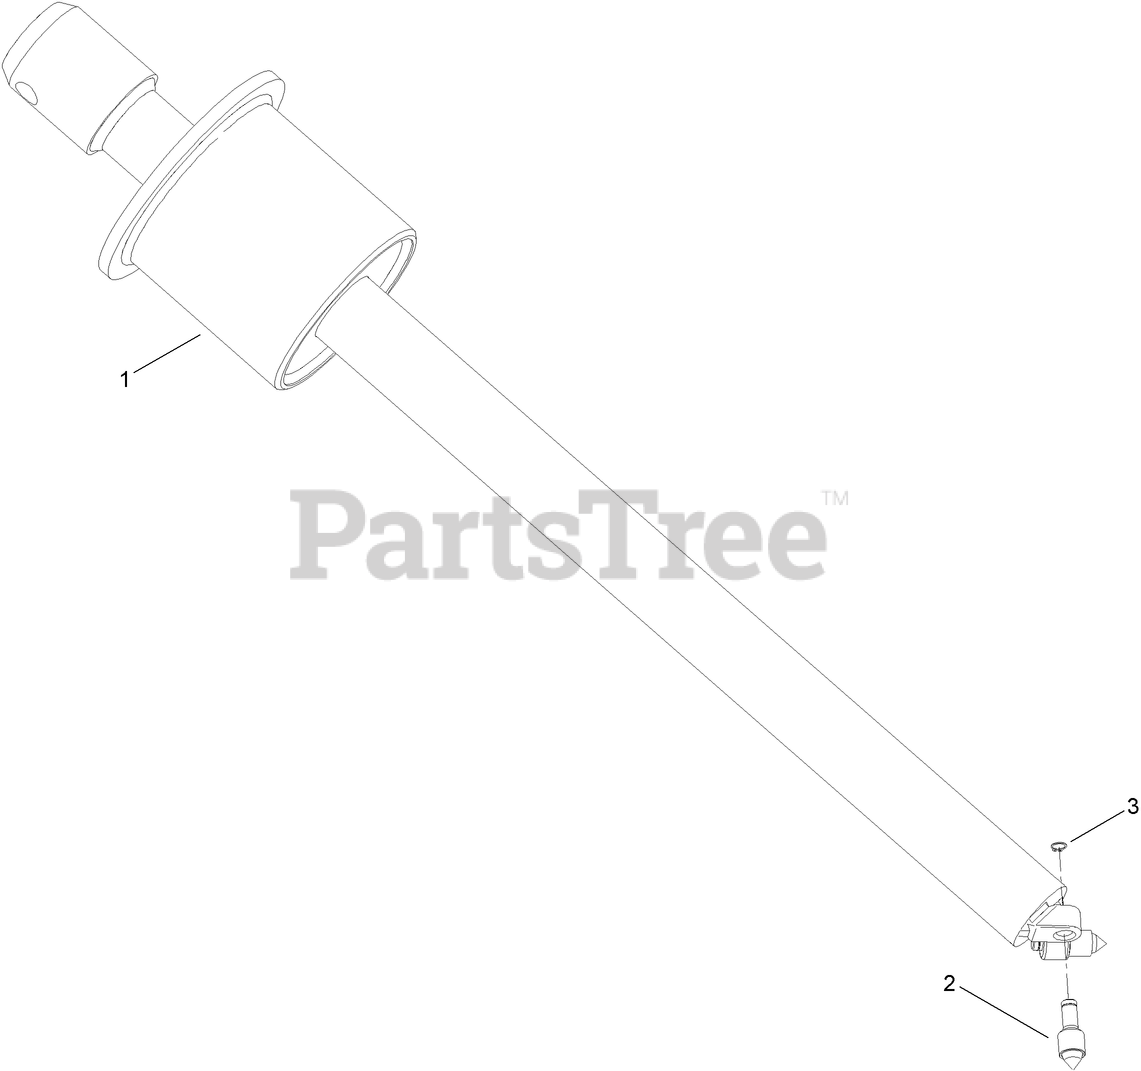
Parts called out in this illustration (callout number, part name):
1	STAKE-ROCK
2	BIT-BULLET, MINI
3	RING-SNAP
